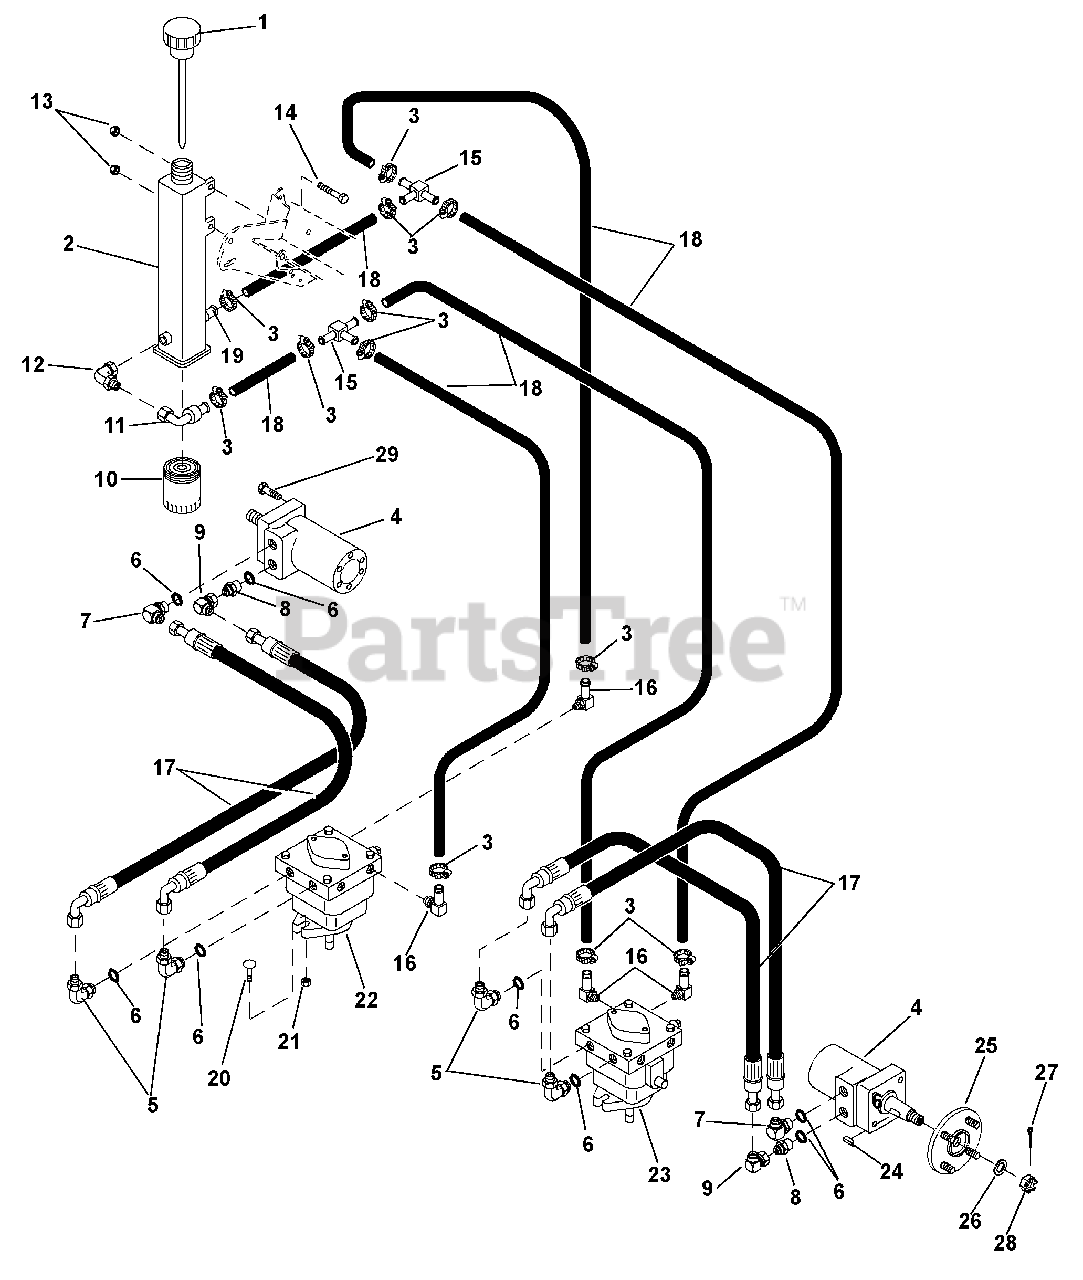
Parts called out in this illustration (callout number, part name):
1	Cap
2	Hydraulic Reservoir, Includes Decal
3	Hose Clamp
4	Wheel Motor
5	Fitting, Includes O-Ring
6	O-Ring, Included With Fitting
7	Fitting, 7/8ORB x 3/4JIC x 90
8	Fitting, ADP 3/4-16 MJIC x 7/8-14MOR
9	Adapter, 3/4 FESW x 3/4MJIC x 90
10	Element, Oil Filter
11	Elbow Fitting
12	Adapter, 2503-6-6
13	Nut, Locking, Nylon M10-1.5
14	Bolt, Hex M10 x 1.5 x 20 Grade 5
15	Tee Fitting
16	Fitting, Adapter .562-18 Steel Thread
17	Hose, High Pressure
18	Hose, Return, 25 Ft. Bulk - Cut to Length
19	Adapter, Straight Fitting
20	Carriage Bolt, Pump Mounting, M10
21	Nut, Locking, Nylon M10-1.5
22	Pump, LH
23	Pump, RH
24	Key, Woodruff .19 x .75 HRD #9
25	Hub, Rear Wheel
26	Shim, .020 x .787 x 1.102
27	Pin, Center .125 x 2.00
28	Castle Nut
29	Bolt, Hex .38-16 x 1.00 Grade 5
